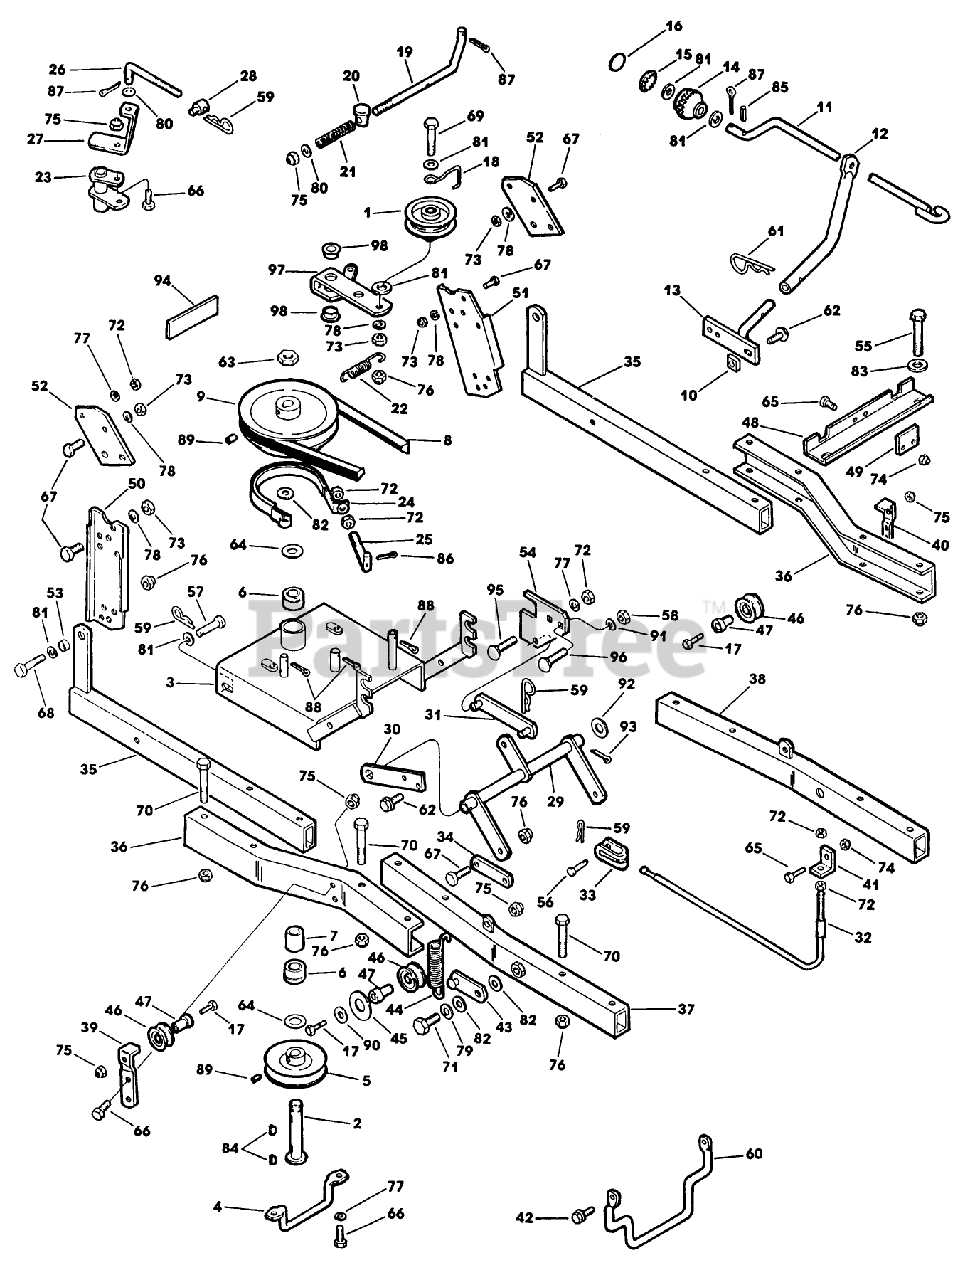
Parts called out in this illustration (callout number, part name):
2	SHAFT AY *NP
12	TUBE-CRANK
14	KNOB
18	RETAINER-BELT
23	CLUTCH ARM ASM MBL
31	LIFT LINK
35	REAR FRAME AY
37	FRONT FRAME AY RH
42	SCREW-THREAD FRMG
51	BRACKET MOUNTING
52	HANGER PLATE
58	NUT
59	PIN - SPRING CLIP
64	WASHER-SHIM
66	SCREW - HEX
72	NUT SS
73	NUT
74	NUT-LOCK, CONE
75	NUT
76	NUT-LOCKING
78	WASHER
81	WASHER
83	WASHER
89	SET SCREW
94	REFLECTOR
